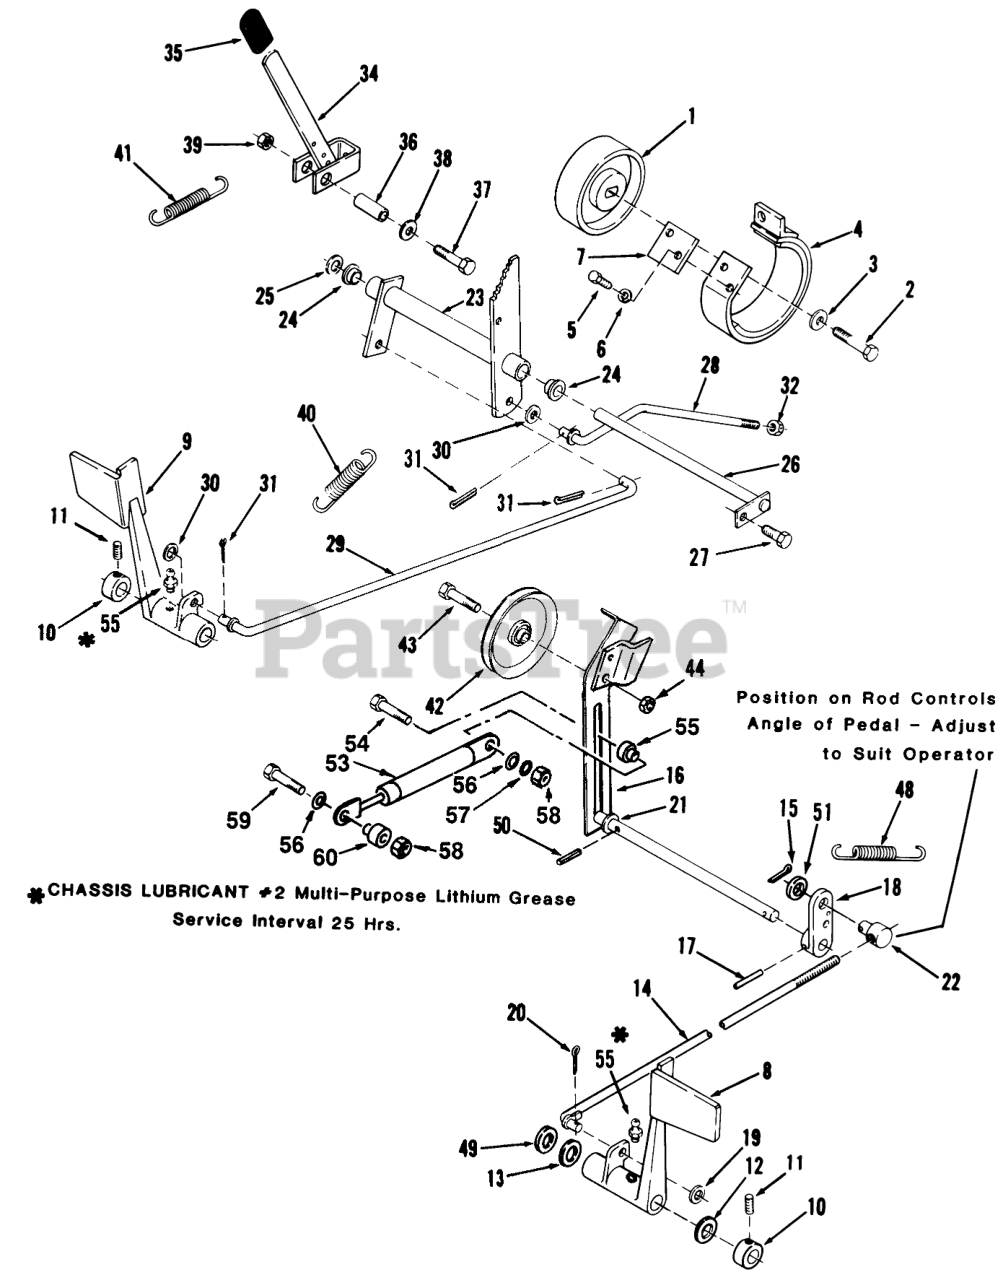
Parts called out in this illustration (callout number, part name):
1	DRUM-BRAKE
2	SCREW-HEX HD CAP
3	WASHER
4	BRAKE BAND ASM
5	H H C S
6	Washer
7	Plate-Stop
8	PEDAL-CLUTCH R
9	Pedal-Brake
10	Collar
11	SCREW-SET
12	WASHER-BOWED
13	WASHER
14	ROD AND GUIDE ASM
15	Cotter Pin
16	Arm-Clutch Idler
17	PIN-SPIROL
18	Arm-Clutch Rod
19	WASHER-NYLON
20	Pop Rivet
21	SHIM-WASHER
22	TRUNNION
23	Bellcrank Assy
24	BUSHING-FLANGED
25	Washer
26	ROD ASM
27	SCREW
28	ROD-REAR BRAKE
30	WASHER-NYLON
31	Pop Rivet
32	NUT
34	ASSY-BRAKE LEVER WAB
35	GRIP
36	SPACER
37	Bolt
38	Washer
39	LOCKNUT-FLANGE
40	SPRING-BRAKE
41	SPRING-EXTENSION
42	PULLEY-IDLER
43	BOLT-SPECIAL HEX
44	NUT
48	SPRING-CLUTCH
49	Washer
50	PIN-SPIROL
51	Washer
52	BRKT-DAMPER B
53	ASS'Y-GAS SPRING
54	Bolt
55	SPACER-SHOULDER-.200
57	Washer
58	Nut
59	Bolt 1/4-20 X 1 1/2
60	SPACER-SHOULDER-.400
